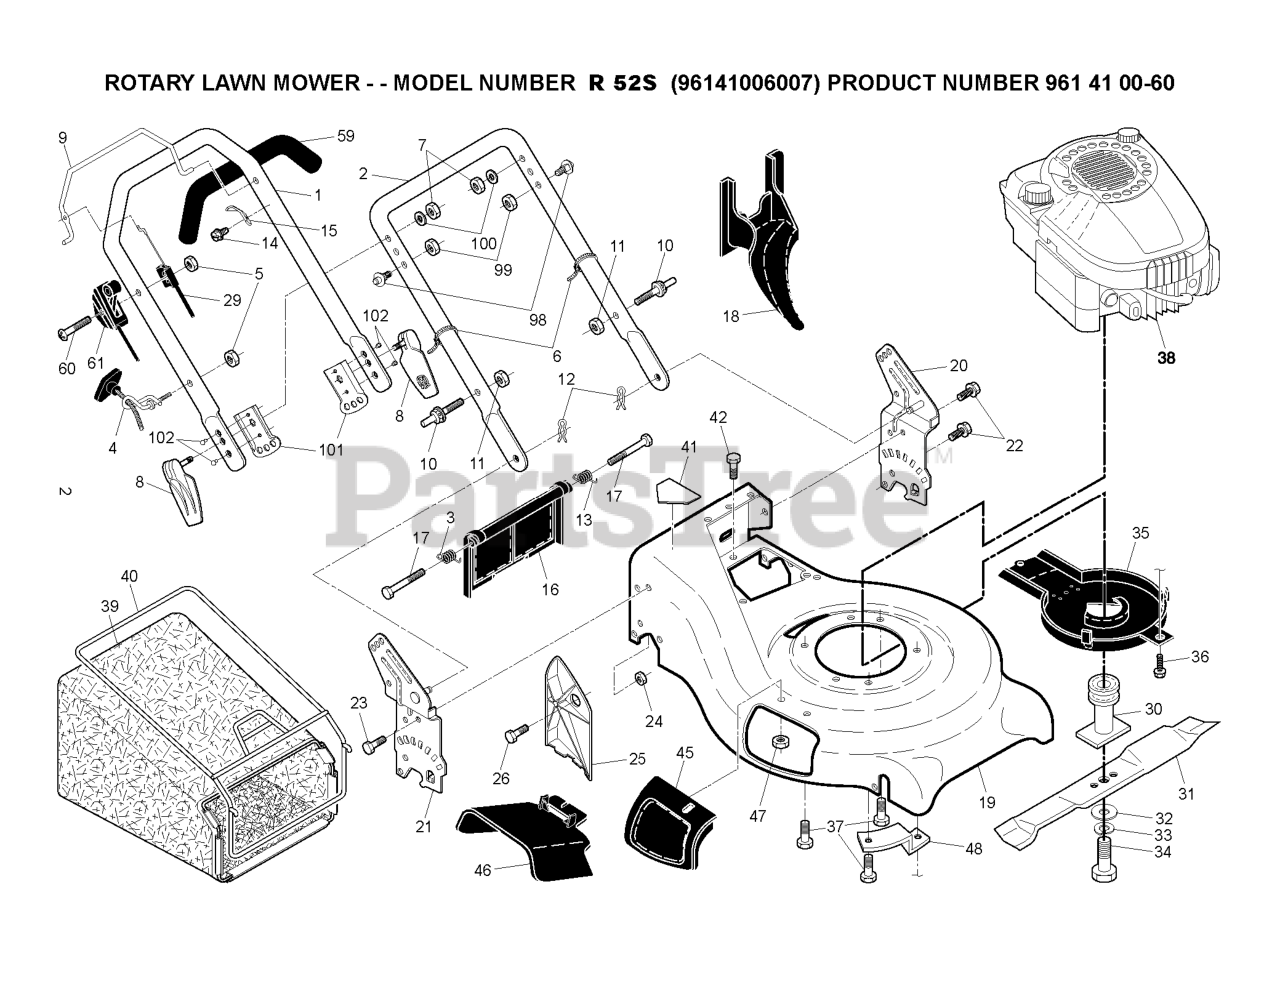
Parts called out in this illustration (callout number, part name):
1	Upper Handle
2	HANDLE.LOWER.21.PNT
3	SPRING.RH.REAR.DOOR.21.RWGD
4	RB GUIDE.ROPE.STD.BLK.ZIN WSL
5	NUT
6	TIE GUIDE
7	Locknut, Hex 1/4-20
8	QUICK.ASM.RELEASE.BLACK
9	BAIL.CONT.COMF.PUSH.ORGANGE.RH
11	NUT.LOCK.5/16-18
12	HAIRPIN COTTER
13	SPRING.LH.REAR.DOOR.21.RWGD
15	BRACKET UPSTOP
16	REAR DOOR ASSEMBLY
18	PLUG.MULCHER.RGD.21.
19	KIT.HSG.21.RGD.MC.ORG.CE
20	BRACKET.HNDL.ASM.21.RWGD.LT.OR
21	BRACKET.HNDL.ASM.21.RWGD.RT.OR
22	BOLT.HEX.HD.WASHER.5/16-18X.75
23	BOLT, HEX HEAD 5/16-18
24	NUT.71038.31-18.HEX.NYLOCK
25	CLIPPING DEFLECTOR
29	ENGINE ZONE CONTROL
30	ADAPTER.BLADE/PULLEY.25M
31	BLADE.21.PUSH
32	WASHER,HARDEN
33	LOCKWASHER
34	SCREW, HEX HD 3/8-24 X 1-3/8
35	DEBRIS SHIELD
36	SCREW.HEX.WSH
37	BOLT 3/8-16X1-1/8
40	FRAME.GBAG.21.RWGD.SC
41	DECAL.INTERNATIONL.CUTFINGER
42	SCREW 14-20 X 5/8
45	MULCHER DOOR ASM.
46	DEFLECTOR, DISCHARGE
48	BRACKET
59	GRIP.HANDLE.FOAM
98	STUD.QUICK.ADJUST
99	NUT.LOCK.5/16-18
100	WASHER.20X8.5
101	BRACKET.ADJ.3POS.GREY
